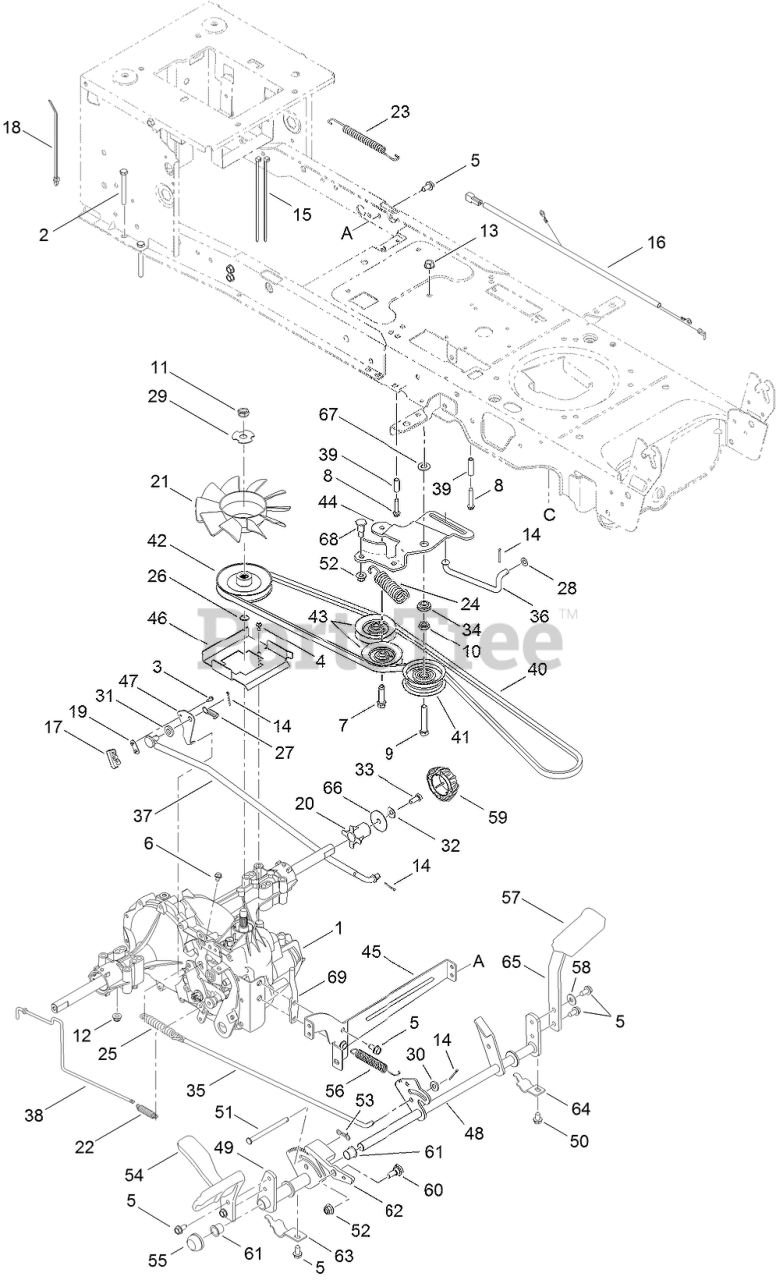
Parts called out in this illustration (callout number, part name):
1	HYDRO TRANSMISSION ASM
2	SCREW-HEX
3	SCREW-HWHTF
5	SCREW-TAP
6	SCREW-TAP
7	SCREW-TAP
8	SCREW-TAP
9	SCREW-HH
10	NUT-JAM
11	NUT-JAM
12	NUT-LOCK, FLANGE
13	NUT-LOCK, FLANGE
14	PIN-COTTER
15	TIE-CABLE
16	HARNESS-JUMPER
17	SWITCH-SPRING, SHORT
18	TIE-CABLE
19	PLATE-INSULATOR
20	SLEEVE
22	SPRING-EXTENSION
23	SPRING-EXTENSION
24	SPRING-EXTENSION
25	SPRING-EXTENSION
26	RING-WIRE
27	SPRING-EXTENSION
28	WASHER-FLAT
29	WASHER-LOCK
30	WASHER-FLAT
31	WASHER-FLAT
32	WASHER-BELL
33	SCREW-HH
34	SPACER-SHOULDER
35	ROD-BRAKE
36	ROD-BYPASS, FOOT PEDAL
37	ROD-CONTROL
38	ROD-BYPASS, HYDRO
39	SPACER
40	BELT-V
41	PULLEY-IDLER, FLAT
42	PULLEY-INPUT
43	PULLEY-IDLER, Y TYPE
44	BRACKET-IDLER, CENTER DOUBLE
45	BRACKET-MOUNTING
46	BRACKET-SUPPORT, BELT DISENGAGE
47	BRACKET-ACTUATOR
48	BRAKE CONTROL ASM
49	BRACKET-PEDAL
50	SCREW-HWH
51	PIN-CLEVIS
52	NUT-LOCK, FLANGE
53	PIN-COTTER
54	PEDAL-CONTROL
55	CAP-PUSH
56	SPRING-EXTENSION
57	PAD-PEDAL, BRAKE
58	WASHER-BELL
59	CAP-HUB
60	BOLT-SHOULDER
61	BEARING-FLANGE
62	LATCH-CRUISE
63	BRACKET-STRAP, PEDAL SUPPORT
64	BRACKET-STRAP, PEDAL SUPPORT
65	BRACKET-PEDAL, BRAKE
66	WASHER-FLAT
67	WASHER-FLAT
68	SCREW-SHOULDER
69	ROD-KEEPER, DRIVE BELT
